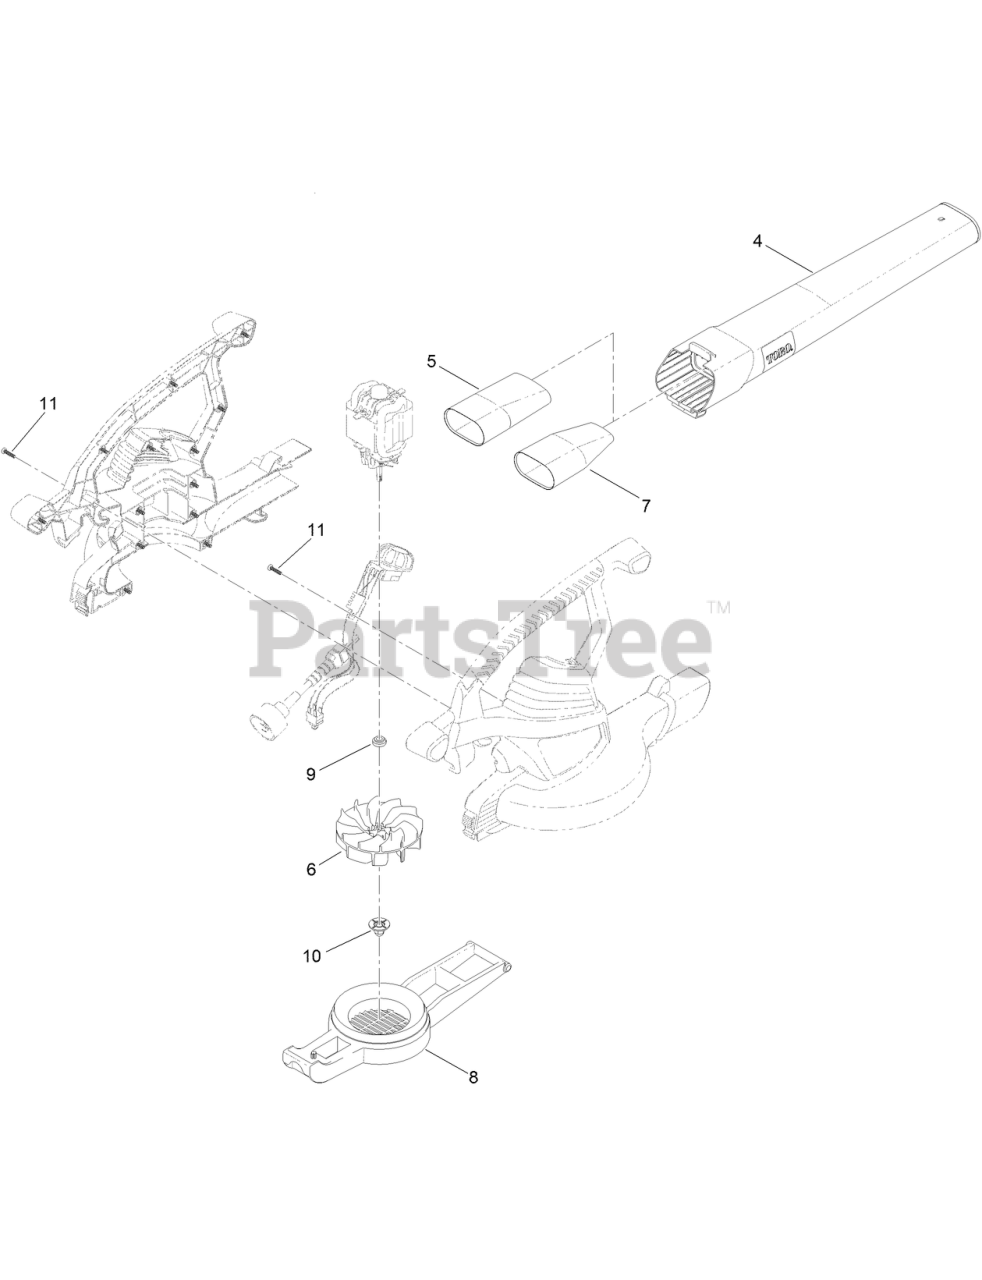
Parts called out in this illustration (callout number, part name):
4	TUBE-BLOWER
5	TUBE-INSERT
6	IMPELLER ASM
7	INSERT-TUBE, MPH
8	COVER-INLET
9	BUSHING-MOTOR
10	NUT-IMPELLER
11	SCREW-PPH
